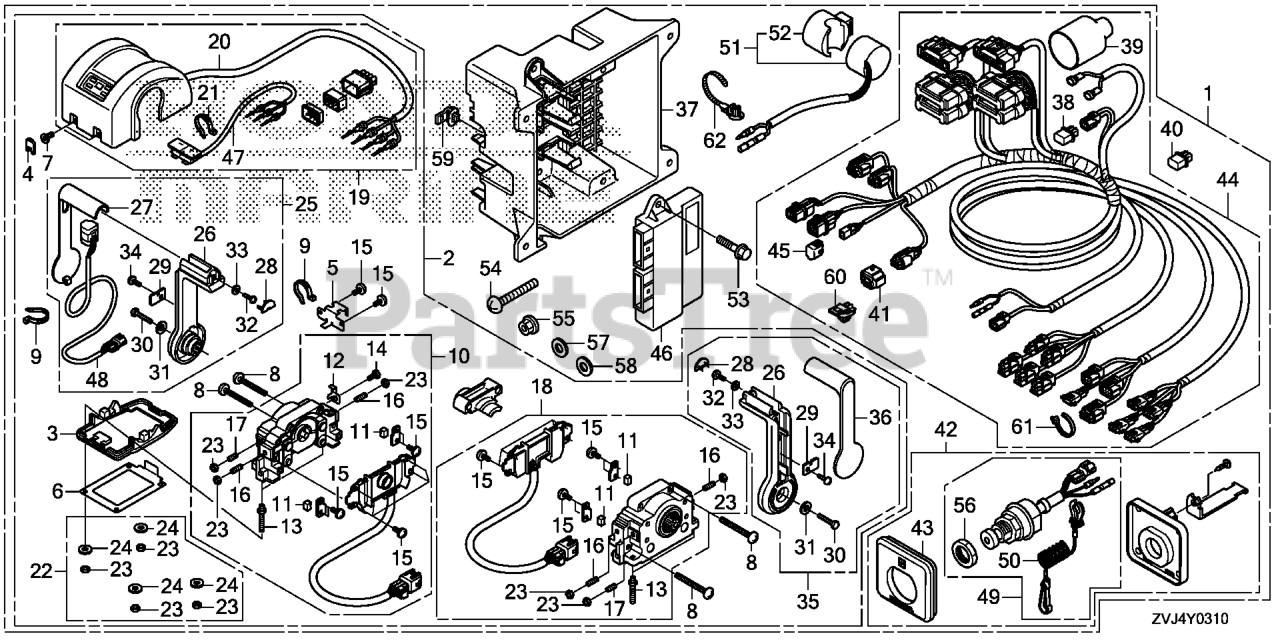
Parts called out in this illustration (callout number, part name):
1	BOX KIT, REMOTE CONTROL (2ND) (TOP MOUNT DUAL)
1	BOX KIT, R/C (2ND)
2	BOX ASSY., REMOTE CONTROL (TOP MOUNT DUAL)(RH)
3	GASKET (TWIN)
4	COVER, CAP
5	PLATE, COVER FIX (TWIN)
6	SHEET, WATERPROOF (TWIN)
7	BOLT, SOCKET
8	SCREW
9	BAND, NYLON
10	HOUSING ASSY., L.
11	SHOE, BRAKE
12	PLATE, HARNESS
13	BOLT, STUD
14	BOLT
16	SCREW SET
17	SCREW SET
18	HOUSING ASSY., R.
19	COVER ASSY., TWIN
20	LED ASSY., COVER (T)
21	BAND, NYLON
22	NUT SET, MOUNTING
24	WASHER
25	LEVER ASSY., L.
26	LEVER
27	PANEL, LEVER (POWER TRIM-TILT)
28	CAP, LEVER
29	PLATE, LEVER PANEL
30	BOLT
31	WASHER
32	SCREW
33	WASHER
34	SCREW
35	LEVER ASSY., R.
36	PANEL, LEVER
37	CASE, CONTROL UNIT
38	TERMINATOR ASSY.
39	COVER, CONNECTOR (NOT AVAILABLE)
40	DUMMY, WATERPROOF CONNECTOR
41	SUSPENSION, CONNECTOR
42	PANEL ASSY., EMERGENCY STOP
43	PANEL, EMERGENCY STOP SWITCH
44	CABLE ASSY., REMOTE CONTROL (2ND)
45	CAP, DUMMY (WPC 4P 090 M) (RED)
46	CONTROL UNIT
46	UNIT ASSY., CONTL
47	SWITCH ASSY., SELECT
48	SWITCH ASSY., POWER TRIM-TILT
49	SWITCH ASSY., EMERGENCY STOP
50	WIRE, EMERGENCY
51	BUZZER ASSY., WARNING
52	SUSPENSION, WARNING BUZZER
53	BOLT, FLANGE (6X20)
54	SCREW, PAN (5X40) DUAL QTY = (8) (SINGLE)
55	NUT, FLANGE (5MM)
56	NUT
57	WASHER, PLAIN (5MM)
58	WASHER, SPRING (5MM)
58	WASHER, SPG (5MM)
59	CLIP, CONNECTOR (DARK BLUE)
60	CLIP, CONNECTOR (DARK BROWN)
61	CLIP, HARNESS BAND (145MM) (BLACK)
62	CLIP, BAND HARNESS (152.4MM) (BLACK)
